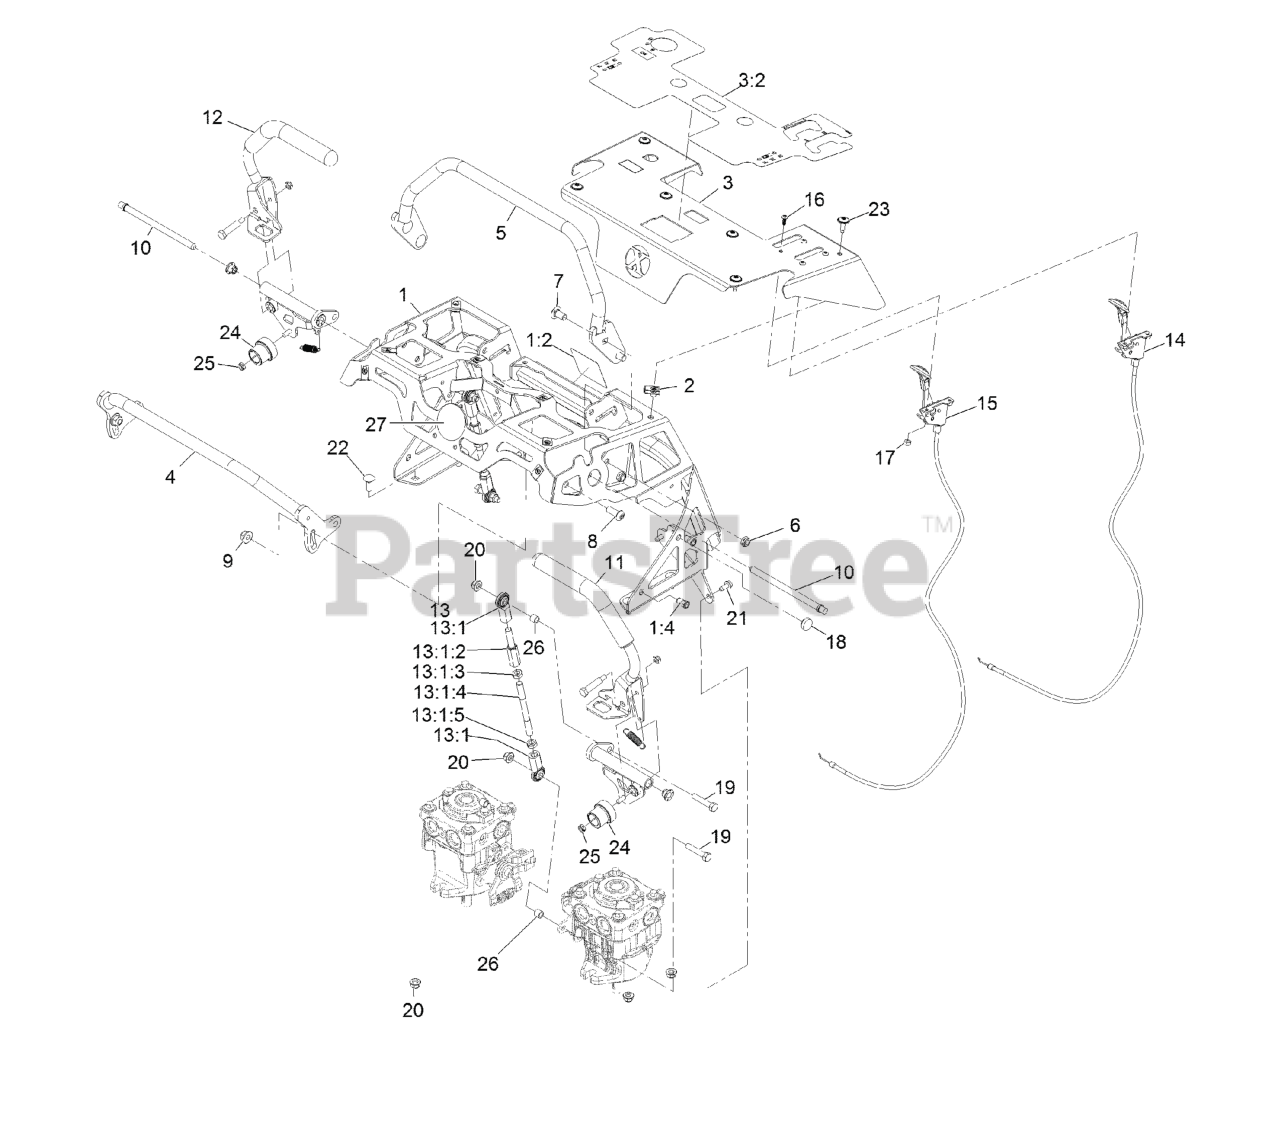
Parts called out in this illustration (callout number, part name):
1	ASM-Ctrl Tower
1:2	DECAL-WARNING
1:4	Nut-Clinch,Hex
3	ASM, Control Panel W/ Decals
3:2	Decal-Control Panel Non-EFI
4	Weld, Front Ref Bar
5	Weld, Rear Ref Bar
7	SCREW-CARR
8	SCREW-HSBH
9	NUT-HF, NI
10	PIN, PIVOT
11	ASM, Motion Control, Lt
12	ASM, Motion Control, Rt
13	ASM, Linkage
13:1	ASM, Motion Control Link
13:1:2	ROD-ADJUSTMENT
13:1:3	NUT-HEX JAM, LH
13:1:4	Link, Motion Control
13:1:5	NUT-HJ
14	CONTROL, CHOKE
15	CONTROL, THROTTLE
16	SCREW, BHCS
17	NUT-LOCK, NI
19	SCREW-HH
20	NUT-HF, NI
21	SCREW-HWH
22	SCREW-CARR
25	NUT-LOCK, NI
27	DECAL-COVER
27	Decal-Cover
